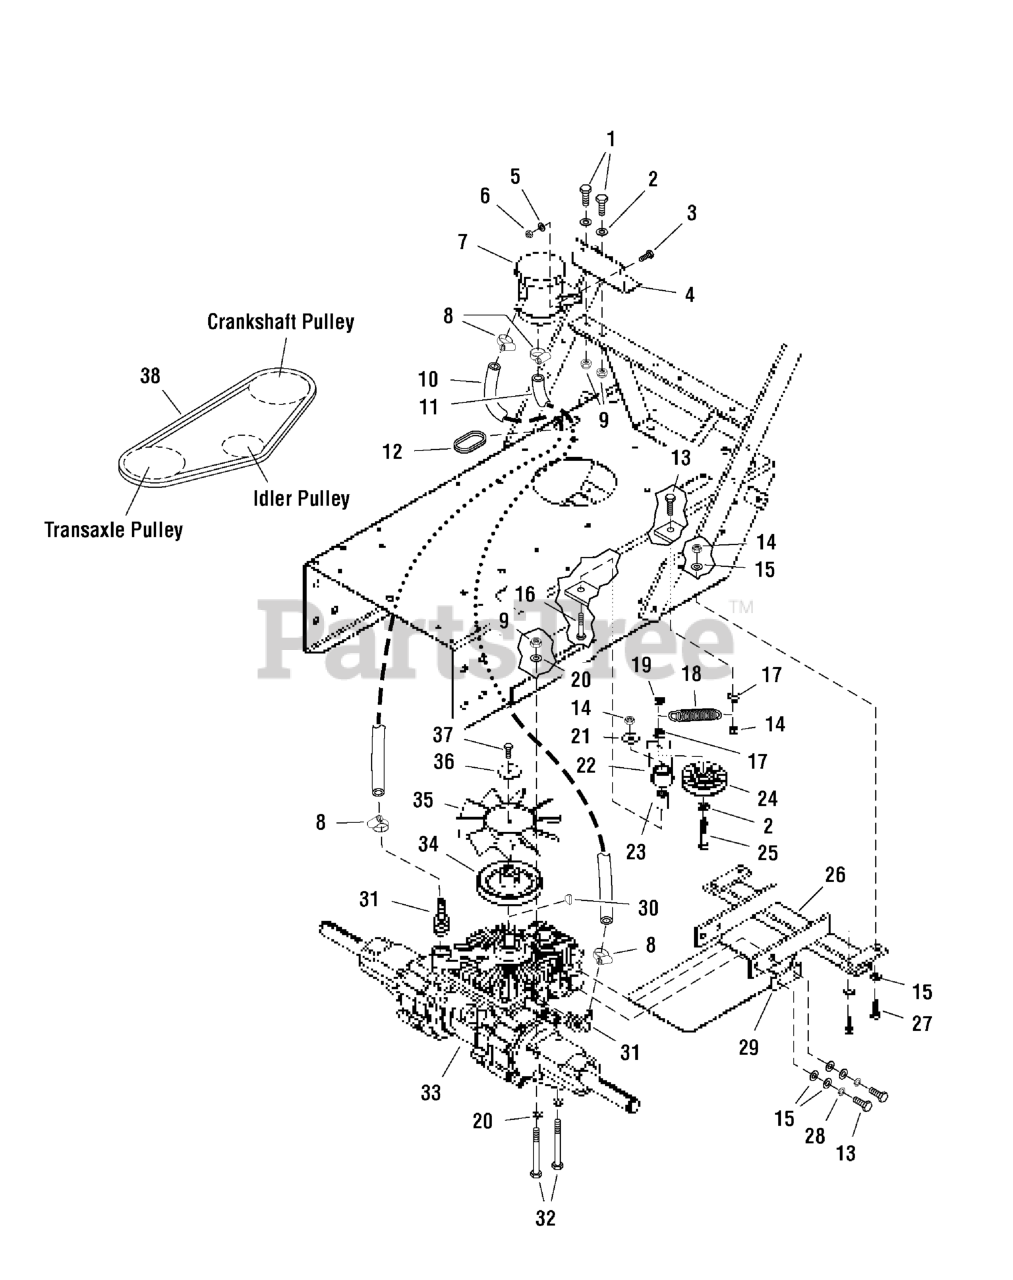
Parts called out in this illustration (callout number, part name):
1	BOLT, 3/8-16 X 1" GD5 CZ
2	WASHER, 3/8 SAE
3	BOLT, 1/4-20 x 3/4
4	BRACKET, Reservoir Mount
5	WASHER, 1/4 SAE
6	NUT, 1/4-20 HEX NYLON LOCK
7	RESERVOIR, Hydraulic
8	CLAMP, #6 Hose
9	NUT, 3/8-16 HEX NYLON LOCK
10	HOSE, 3/8 PUSH-LOCK, 26.00
11	HOSE, 3/8" PUSH-LOCK, 31"
12	GROMMET, 1-1/4"
13	BOLT, 5/16-18 x 1-1/4
14	NUT, 5/16-18 Hex Nylon Lock
15	WASHER, 5/16" SAE
16	BOLT, 5/16-18 x 1-3/4
17	NUT, 5/16-18 HEX SERRATED FLANGE (LARGE)
18	SPRING, Extension
19	NUT, 3/8-16 Hex Side Lock
20	WASHER, 3/8" GD9
21	WASHER, 5/16" Fender
22	IDLER ARM ASSEMBLY
22	BUSHING, Brass
23	SPACER, .32 x .75 x 1.06
24	IDLER PULLEY
25	BOLT, 3/8-16 X 2, GD5, CZ
26	TRANSMISSION BRACE
27	BOLT, 5/16-18 X 1 GD5 YZ
28	WASHER, 5/16 LOCK CZ
29	BRACE, Hydro Spacer
30	KEY, #61 Woodruff
31	FITTING, 90 Degree
32	BOLT, 3/8-16 X 3-1/2" GD5 CZ
33	TRANSAXLE (model 751)
34	TRANSMISSION INPUT PULLEY
36	WASHER, .265 x 1.50 x .109
37	BOLT, Loctite Patch, 1/4-20 x 3/4
38	Belt, Transmission Drive
